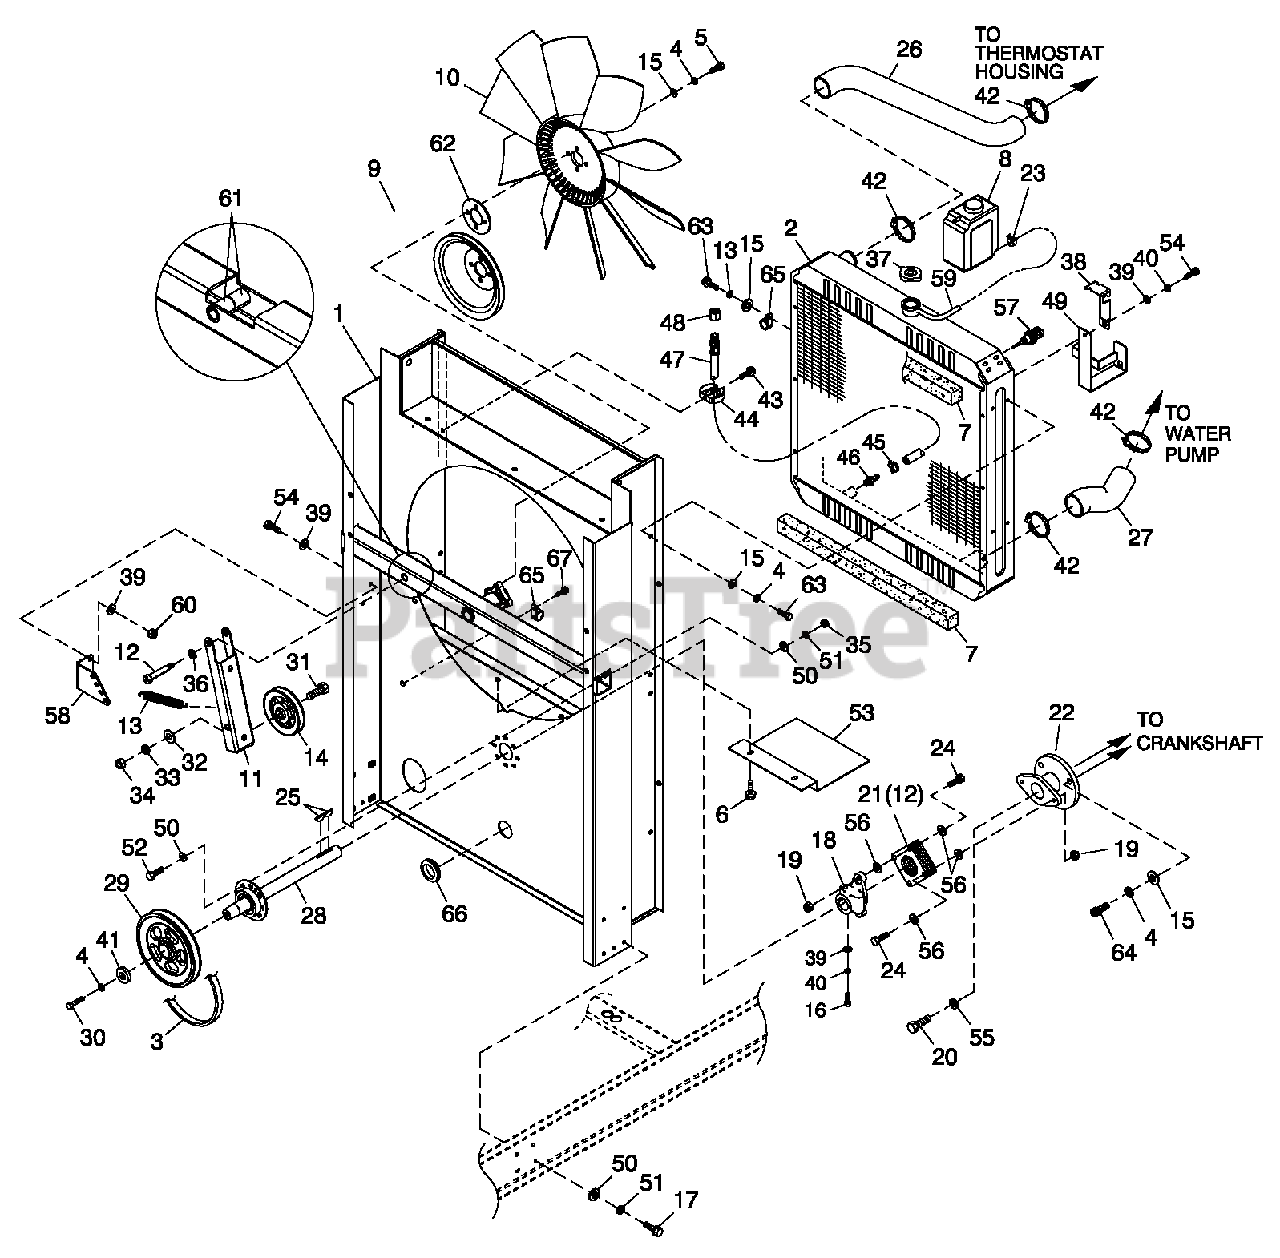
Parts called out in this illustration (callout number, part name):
1	WELDMENT RADIATOR SUPPORT C5
2	RADIATOR 680 X 680 X 70 CPL
3	V-BELT 31/64" X 62-3/8"
4	WASHER LOCK M10
5	SCREW HHC M10-1.5 X 30 C10.9
6	SCREW THF M6-1 X 16 N WA Z/JS
7	TAPE FOAM 1 X 1 (26.75" LG)
8	TANK COOLANT RECOVERY
9	PULLEY FAN V-GROOVE 9"
10	FAN 26" LH ROTATION
11	ARM BELT TENSIONER
12	SHOULDER BOLT 1/2 X 2-1/4"
13	SPRING TENSION CPL
14	PULLEY V-BELT 4" FLANGED
15	WASHER FLAT 3/8-M10 ZINC
16	SCREW HHC M8-1.25X45C8.8
17	SCREW HHFC M6-1.0X20 G8.8
18	HUB FLEX PLATE
19	NUT HEX LOCK 5/16-24 NY INS
20	SCREW HHC M12-1.5X60G8.8
21	DISK FLEX
22	COUPLING HUB FLEX (MACH)
23	CLAMP HOSE BAND 1/4
24	SCREW HHC 5/16-24X1.124
25	KEY WOODRUFF 4X 1 9D
26	HOSE RADIATOR UPPER CPL
27	HOSE LOWER RAD CPL C5 6.8L
28	ASSY BRG/SHAFT CPL FANDRIVE
29	PULLEY 6.5" DIA MACHINED (6.8L 100KW)
30	SCREW HHC M10-1.5X30G8.8
31	SCREW HHC 1/2-13X2" G8
32	WASHER FLAT 1/2 ZINC
33	WASHER LOCK 1/2
34	NUT HEX 1/2-13 STEEL
35	NUT HEX M6X 1.0 G8 YEL CHR
36	WASHER NYLON .50 X .87 X .06
37	CAP RADIATOR 13 PSI
38	BRACKET, SIGNAL CONDITIONER
39	WASHER FLAT 5/16-M8 ZINC
40	WASHER LOCK M8-5/16
41	SPACER .5 X 1.5 X .25 STL/ZINC
42	CLAMP HOSE #28 1.32-2.25
43	SCREW HHTT M4-0.7 X 8 BP
44	SPRING CLIP HOLDER .37-.62
45	CLAMP HOSE .38-.87
46	BARBED STR 3/8 NPT X 3/8
47	HOSE DRAIN ASSY 28"
48	CAP HEX 1/4 NPT BRASS
49	BRACKET COOLANT TANK
50	WASHER FLAT 1/4-M6 ZINC
51	WASHER LOCK M6-1/4
52	SCREW HHC M6-1.0X20G8.8
53	SHIELD RADIATOR
54	SCREW HHC M8-1.25X20G8.8
55	WASHER LOCK M12
56	WASHER FLEX (THIN)
57	PROBE COOLANT LEVEL 3/8-18NPTF
58	BRACKET TENSIONER SPRING
59	HOSE 9/32 ID (43"LG)
60	NUT HEX LOCK M8-1.25 NY INS
61	BEARING SLEEVE 1/2/ X 3/4 X 1
62	SPACER CPL COOLING FAN 1/8"
63	SCREW HHC M10-1.5X20C8.8
64	SCREW SHC M10-1.5X 35 G12.9
65	CLAMP STUVNL.62 X . 406 Z
66	GROMMET 1.37 X .06 X 1.00
67	SCREW HHTT M6-1.0X 16ZYC
